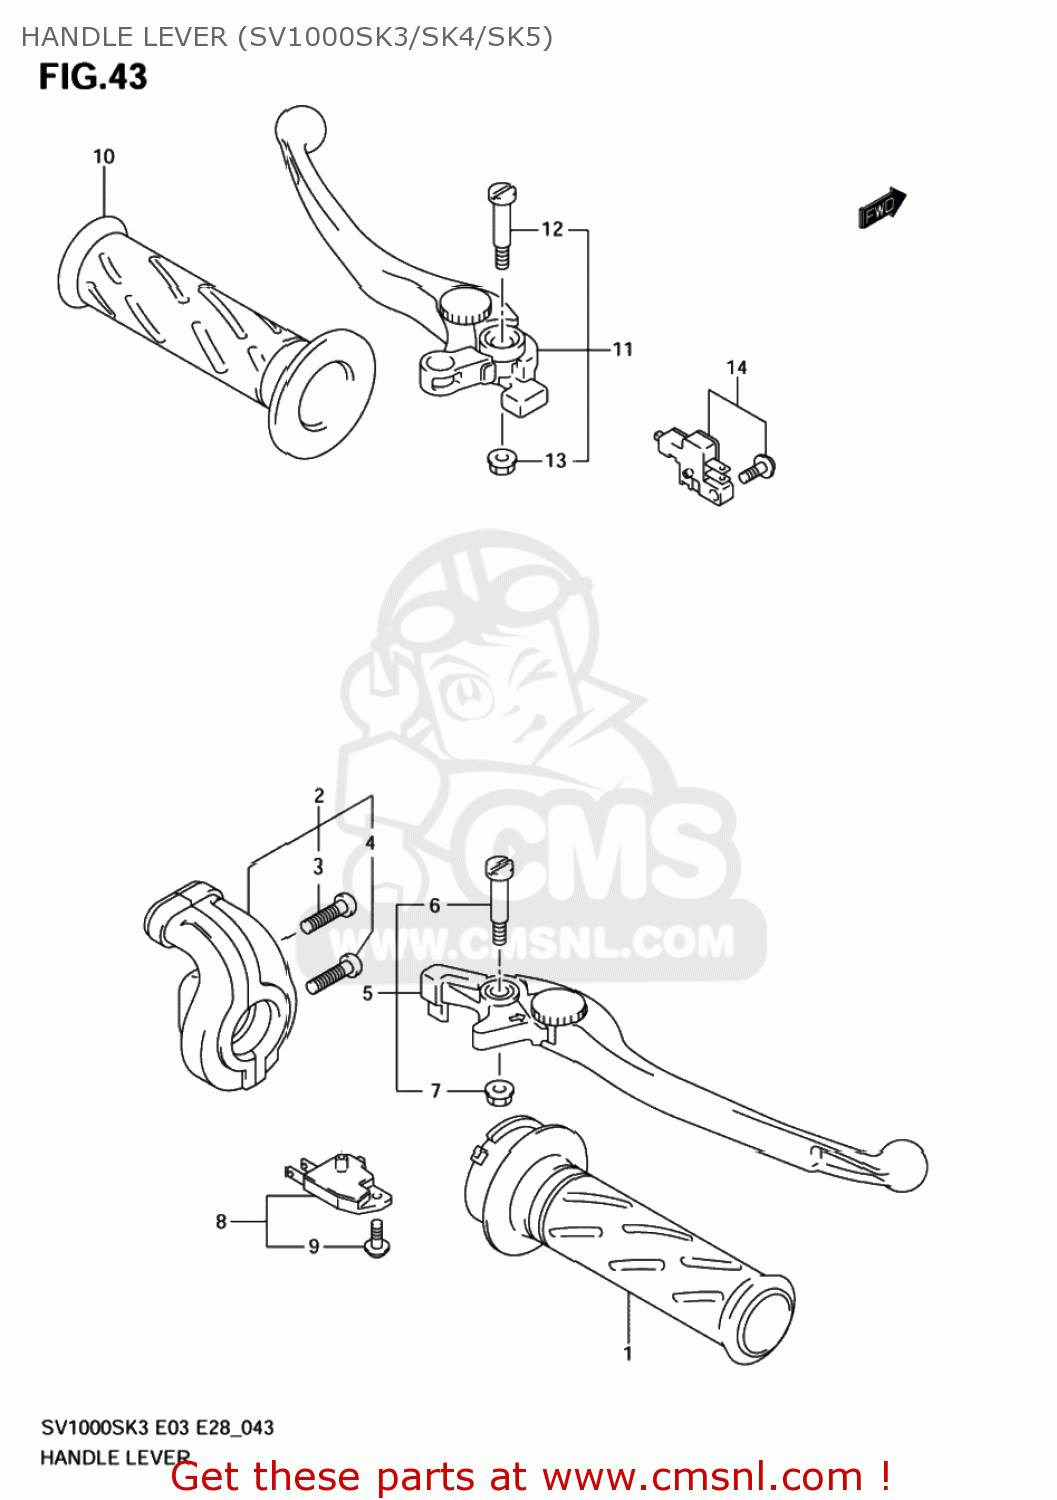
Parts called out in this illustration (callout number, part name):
1	GRIP,THROTTLE
2	CASE ASSY,THROTTLE
3	SCREW(5X25)
4	SCREW
5	LEVER ASSY,BRAKE
6	BOLT,LEVER PIVOT
7	NUT
8	SWITCH ASSY,ST
9	SCREW
10	GRIP,LEFT
11	LEVER ASSEMBLY,CLUTCH
12	BOLT,LEVER PIVOT
13	NUT
14	SWITCH ASSY,CLUTCH
